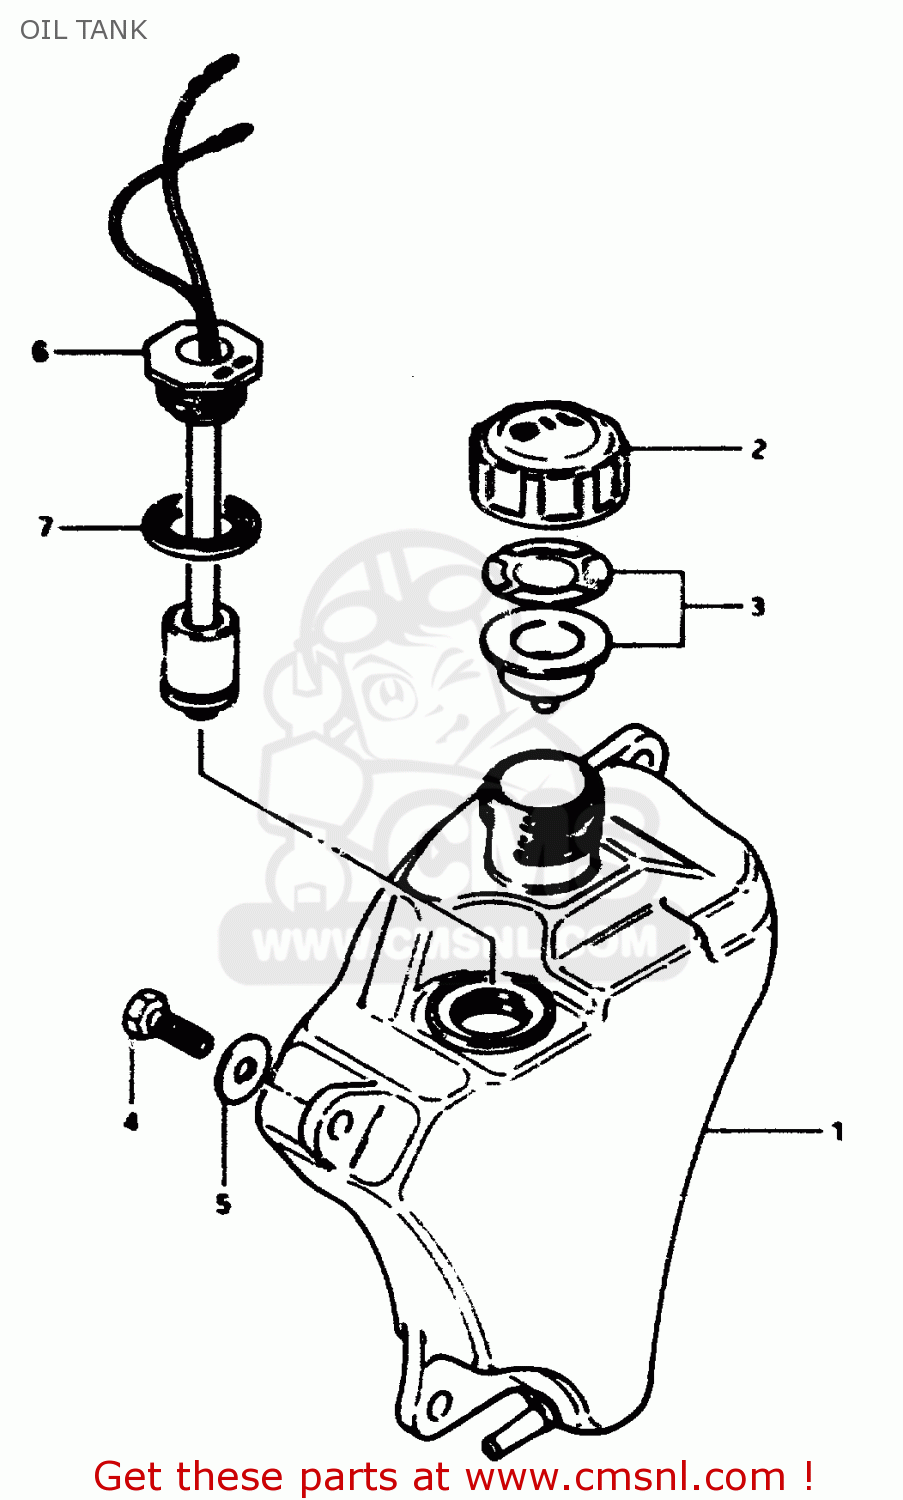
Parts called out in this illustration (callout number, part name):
1	TANK, OIL
2	CAP,OIL TANK
3	GASKET SET (NAS)
4	BOLT, UPPER
5	WASHER
6	SWITCH, OIL LEVEL
7	GASKET (NAS)
